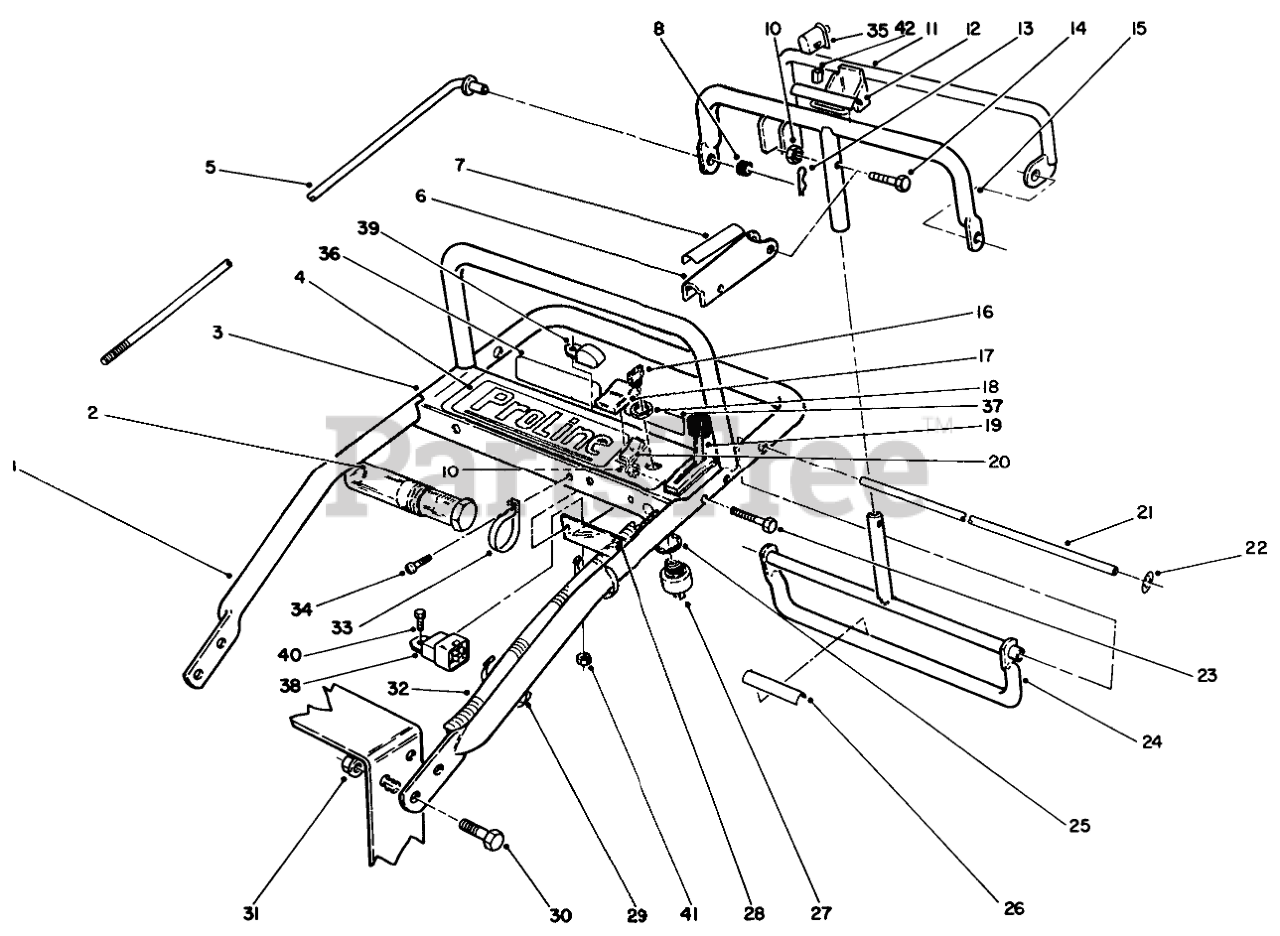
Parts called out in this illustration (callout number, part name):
1	Handle-Upper
2	TUBE-MANUAL
3	Panel-Control
4	DECAL-CONTROL PANEL
5	ROD-CONTROL
6	Lever-Parking Brake
7	DECAL-LEVER, PARKING
8	GROMMET-RUBBER
10	NUT-LOCK, NI
11	Bail
12	DECAL
13	PIN-COTTER
14	SCREW-SHH
15	Bar
16	KEY-IGNITION
17	BOOT-SWITCH
18	NUT-HH
19	CONTROL-THROTTLE
20	SWITCH
21	PIVOT ROD
22	NUT-PUSH-ON, CIRCULAR
23	SCREW-SHH
24	Control Pivot
25	WASHER-TOOTH, INTERNAL
26	DECAL
27	Switch-Off/On (Incl. Ref. #16, 18, & 25)
28	Panel-Bottom
29	TIE-CABLE
30	SCREW-HHF
31	NUT-HF
32	Wire Harness
33	CLAMP-R
34	SCREW-HWHTF
35	SWITCH-BAIL
36	DECAL-INSTRUCTION, SAFETY
37	DECAL-INSTRUCTION
38	RELAY
39	Module
40	SCREW-HH
41	NUT-LOCK, NI
42	CONNECTOR-BODY
